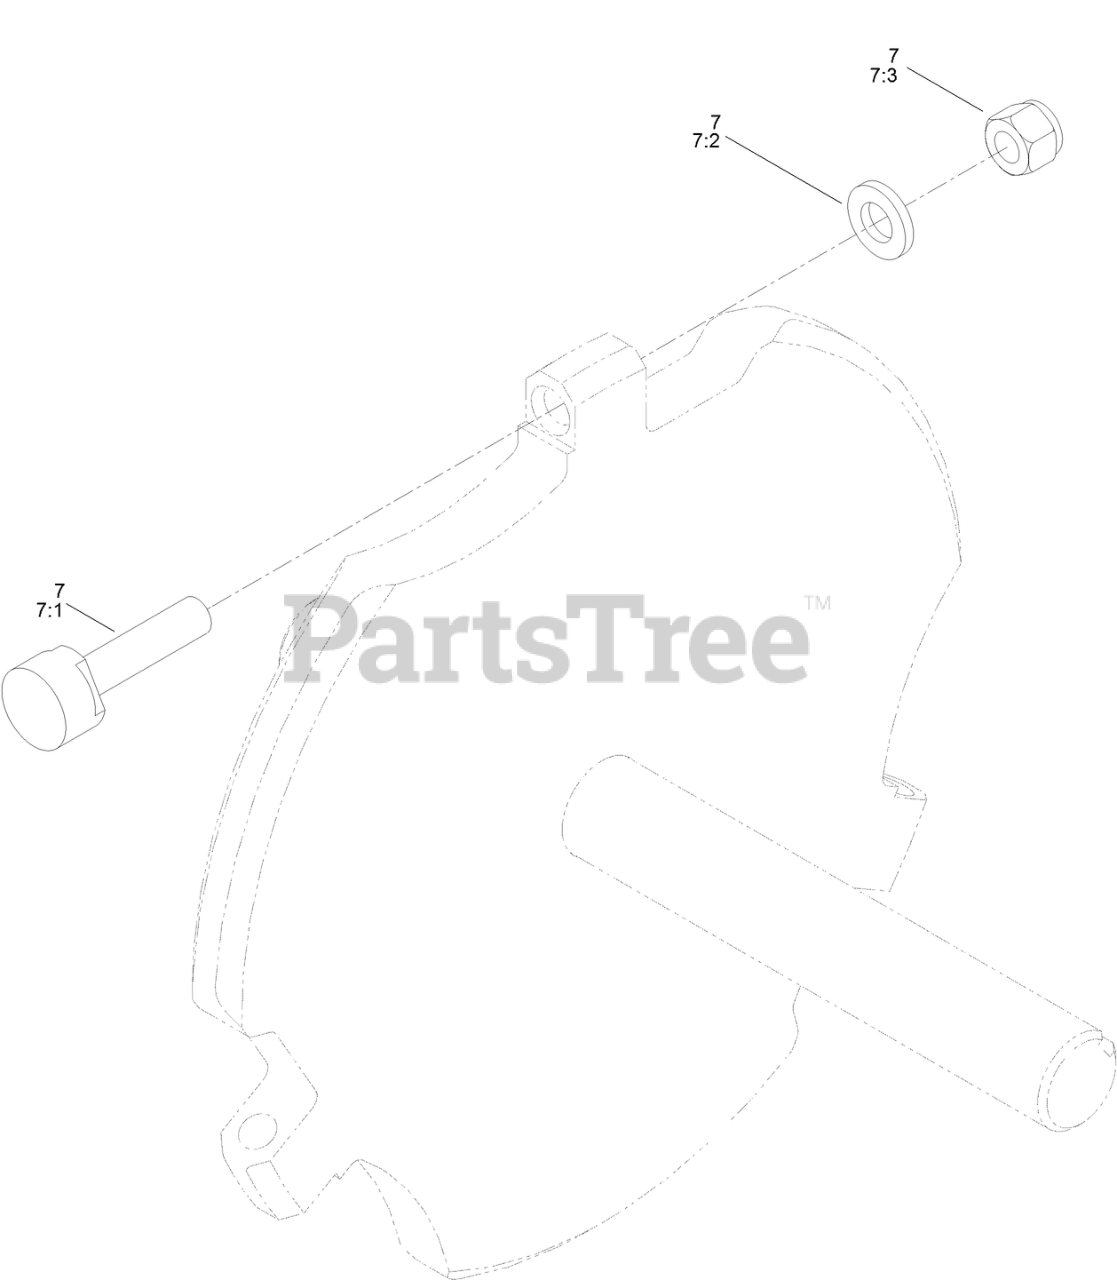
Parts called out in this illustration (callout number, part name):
7	GRINDER TOOTH KIT (3-PACK)
7:1	TOOTH-GRINDER
7:2	WASHER-HARDENED
7:3	NUT-LOCK
